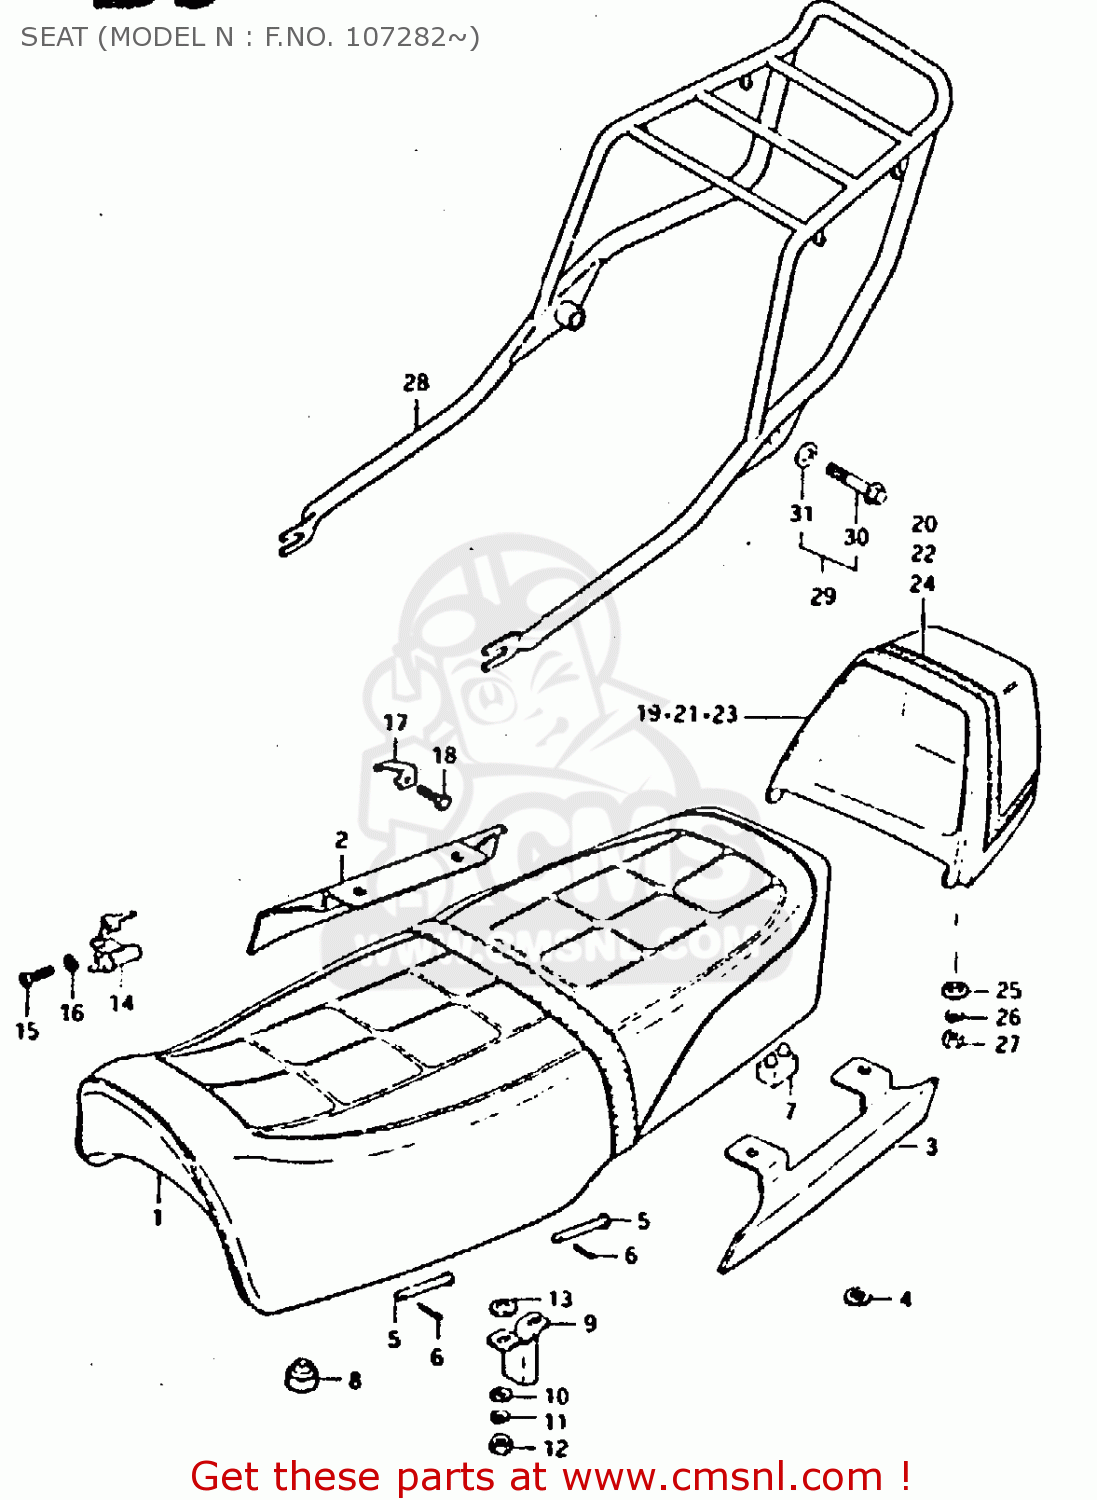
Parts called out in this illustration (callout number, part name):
1	SEAT (BLACK)
2	MOULDING, RH (RED)
3	MOULDING, LH (RED)
4	NUT
5	PIN
6	PIN
7	CUSHION
8	CUSHION
9	STRIKER,SEAT LOCK
10	WASHER
11	LOCK WASHER
12	NUT 6MM
13	WASHER(6.5X18X1)
14	LOCK ASSY,SEAT
15	SCREW
16	LOCK WASHER
17	SPRING,HELMET HOLDER
18	BOLT 5X16
19	COVER, SEAT TAIL (WHITE)
20	TAPE
21	COVER, SEAT TAIL (RED)
22	TAPE
23	COVER, SEAT TAIL (BLUE)
24	TAPE (BLUE & WHITE)
25	WASHER
26	LOCK WASHER
27	NUT 6MM
28	CARRIER, SPORTS
29	BOLT SET, CARRIER
30	BOLT
31	WASHER(10.3X25X1.5
